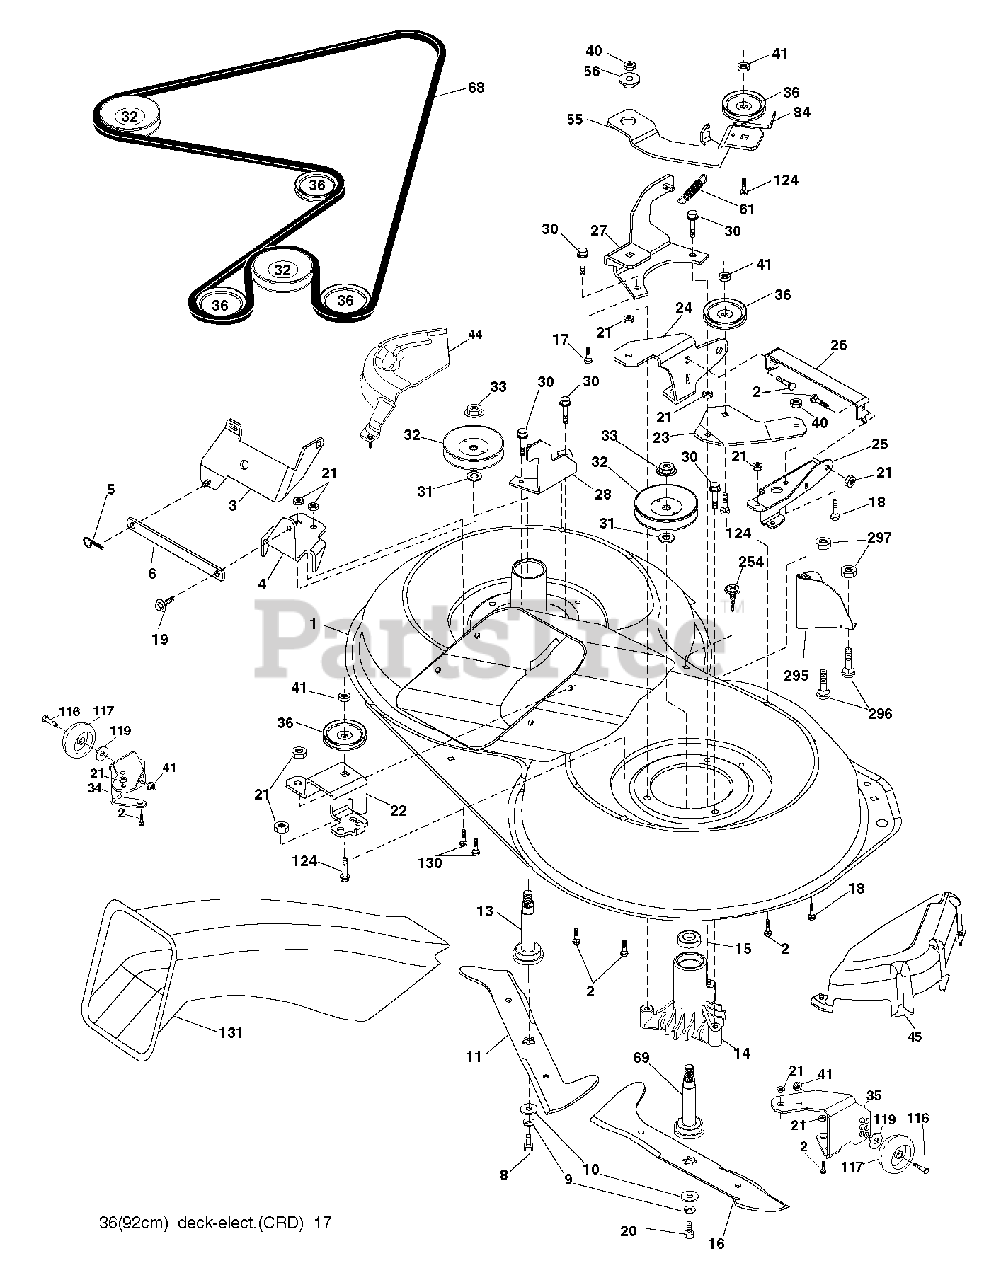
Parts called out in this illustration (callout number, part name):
2	BOLT
3	BRACKET
5	RETAINER-SPRNG RB
6	BAR SWAY
9	LOCKWASHER
10	WASHER.BLADE
13	SHAFT ASM VENT
14	HSG MANDREL
17	BOLT.3/8-14X1.25
18	BOLT
19	BOLT SHD 5/16-18
21	LOCKNUT
24	BRACKET
25	BRACKET
28	BRACKET
30	SCREW, WASHER HEAD
31	WASHER.SPACER.MANDREL
32	PULLEY MANDREL
33	NUT.FLANGE.LOCK.TOP
36	PULLEY.IDLER.4.25
40	LOCKNUT
41	NUT LOCK FLG 3/8-16 UNC
45	MANDREL COVER
56	SPACER.RETAINER.MOWER
69	SHAFT.ASM.W/LWR.BRG.RH.THREAD
84	KEEPER, BELT IDLER
116	BOLT.SHOULDER.3/8-16X3-5/8
117	WHEEL. GUAGE RALLY
124	BOLT.3/8-16X1.50
131	CHUTE BAGGER
254	SCREW 3/8-16X1
296	BOLT
297	NUT CENTERLOCK
